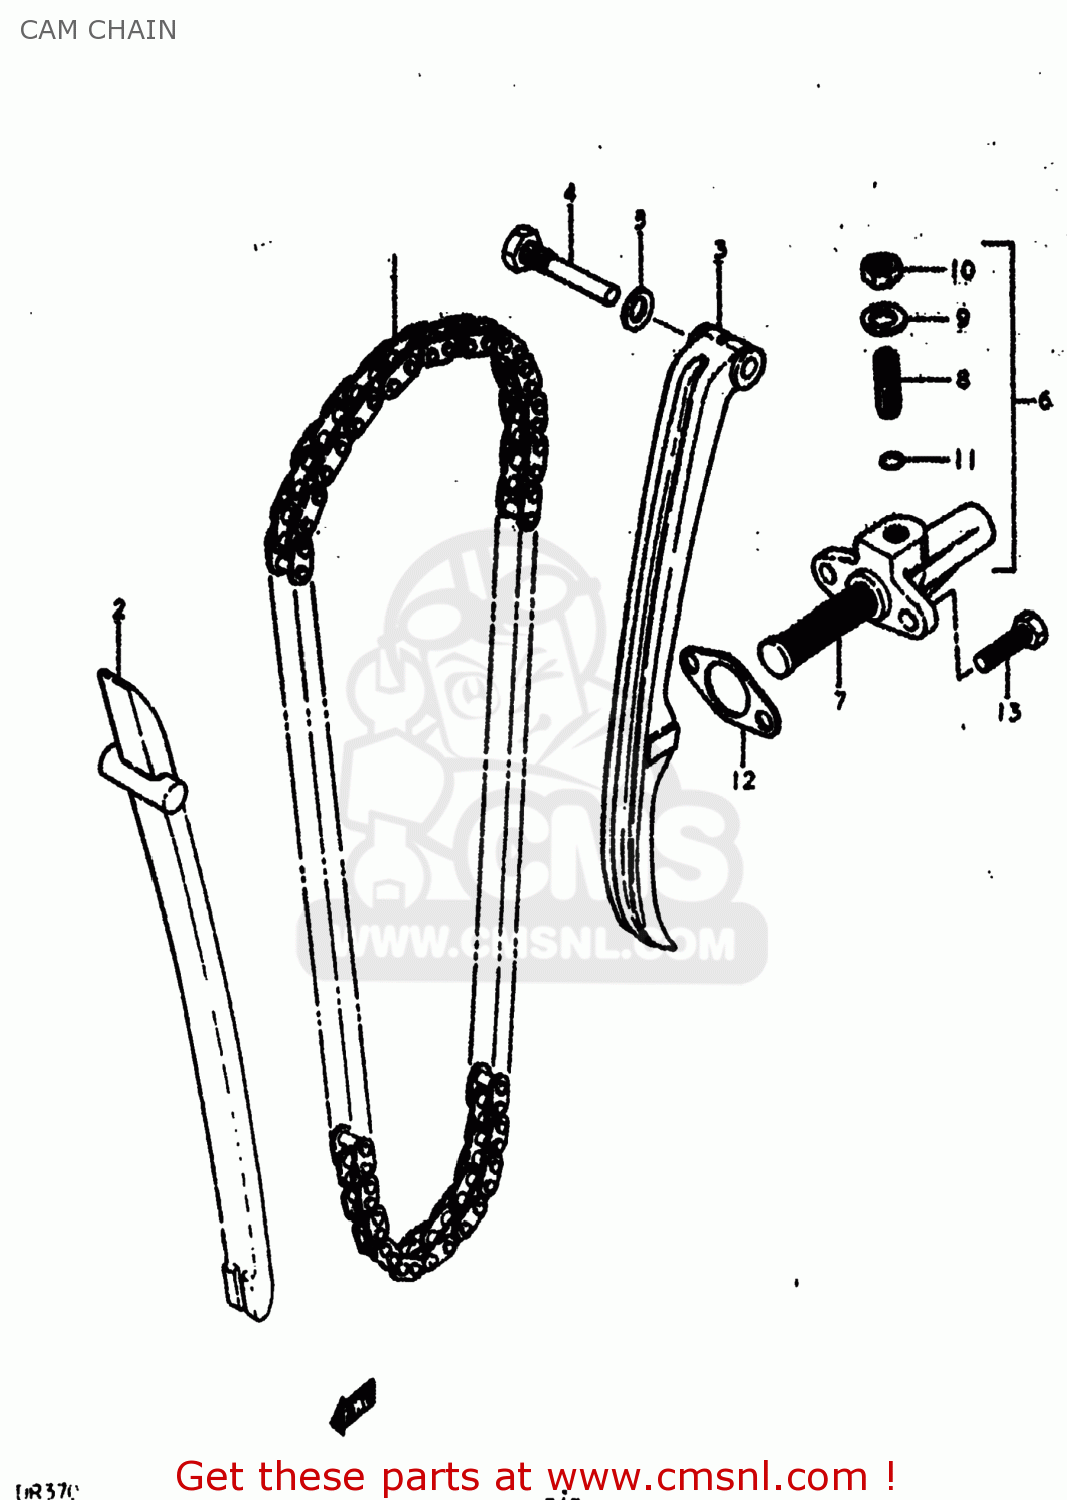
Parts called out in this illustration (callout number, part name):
1	CHAIN,CAMSHAFT DRIVE
2	GUIDE,CAM CHAIN
3	TENSIONER,CAM CHAIN
4	BOLT,CAM CHAIN TENSIONER
5	GASKET 8.2X14X1 (NAS)
6	ADJUSTER ASSEMBLY,TENSIONER
7	SPRING
8	SCREW
9	WASHER
10	NUT
11	O-RING
12	GASKET,TENSIONER ADJUSTER (NAS)
13	BOLT
